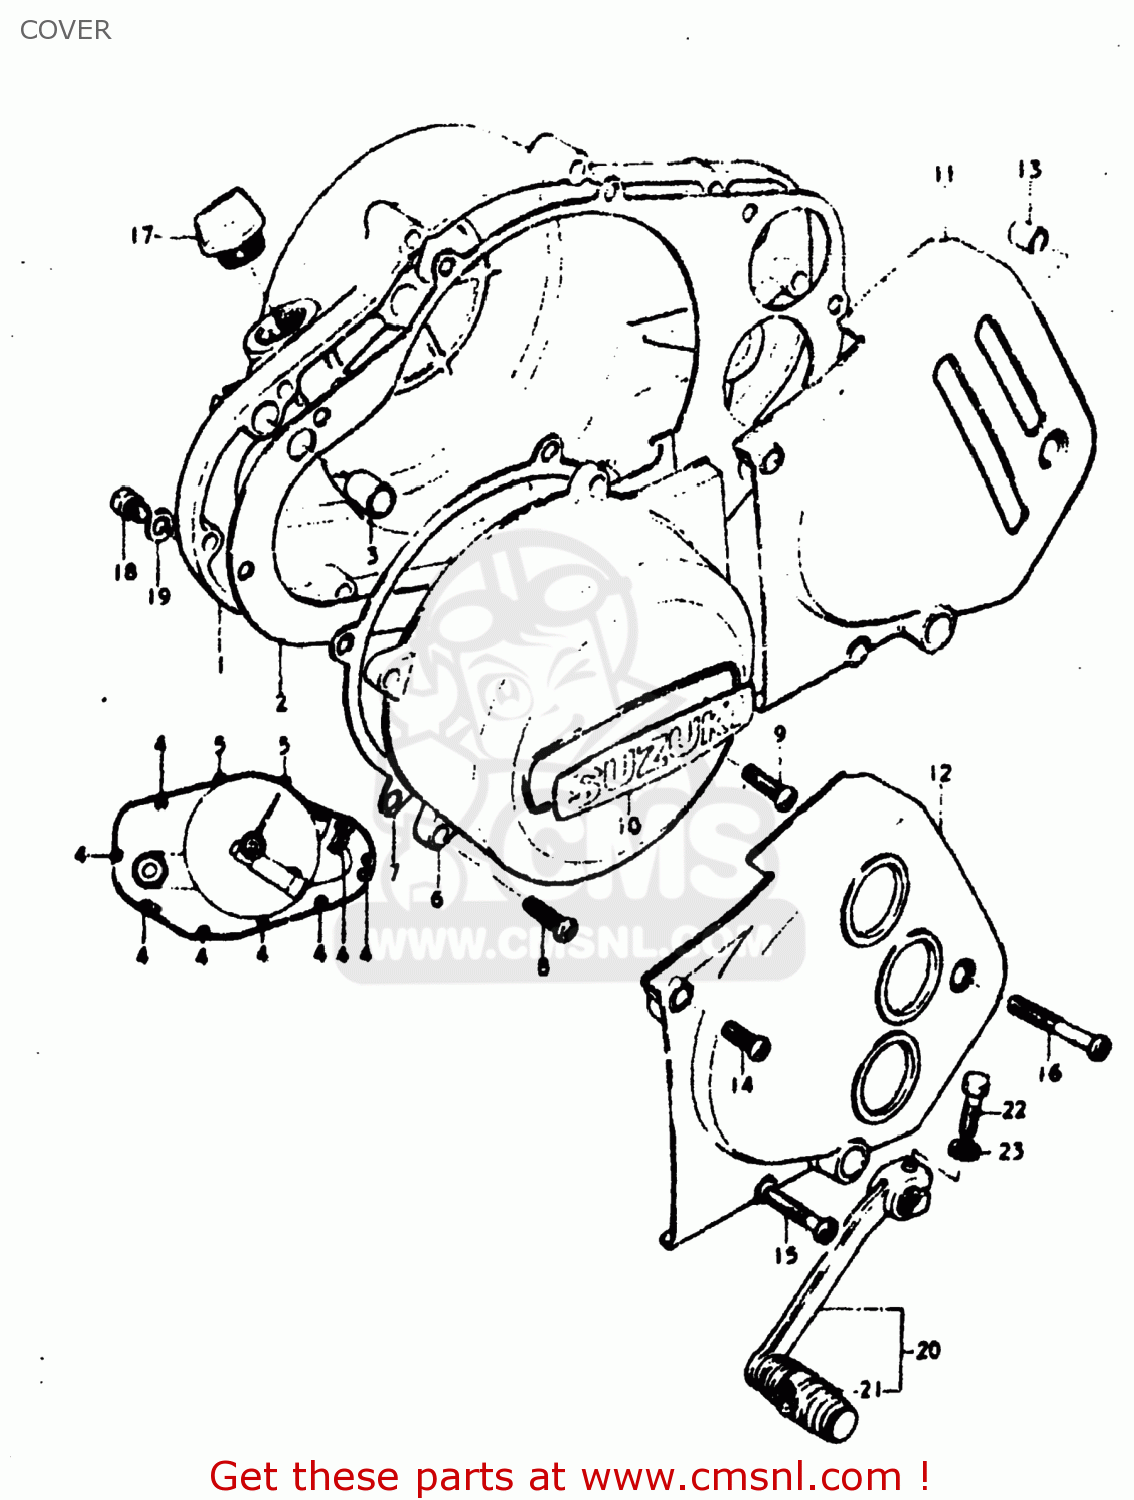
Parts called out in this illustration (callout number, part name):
1	COVER,CLUTCH
2	GASKET,CLUTCH COVER (MCA)
3	PIN
4	SCREW
5	SCREW (6X35)
6	COVER
7	GASKET,MAGNETO COVER (MCA)
8	SCREW
9	SCREW
10	EMBLEM
11	COVER,SPROCKET
12	COVER,SPROCKET
13	PIN
14	SCREW
15	SCREW (6X35)
16	SCREW
17	PLUG,OIL FILTER
18	SCREW(6X10)
19	GASKET(6.2X11X1) (NAS)
20	LEVER ASSEMBLY,GEAR SHIFTING
21	RUBBER,GEAR SHIFT PEDAL
22	BOLT
23	LOCK WASHER
